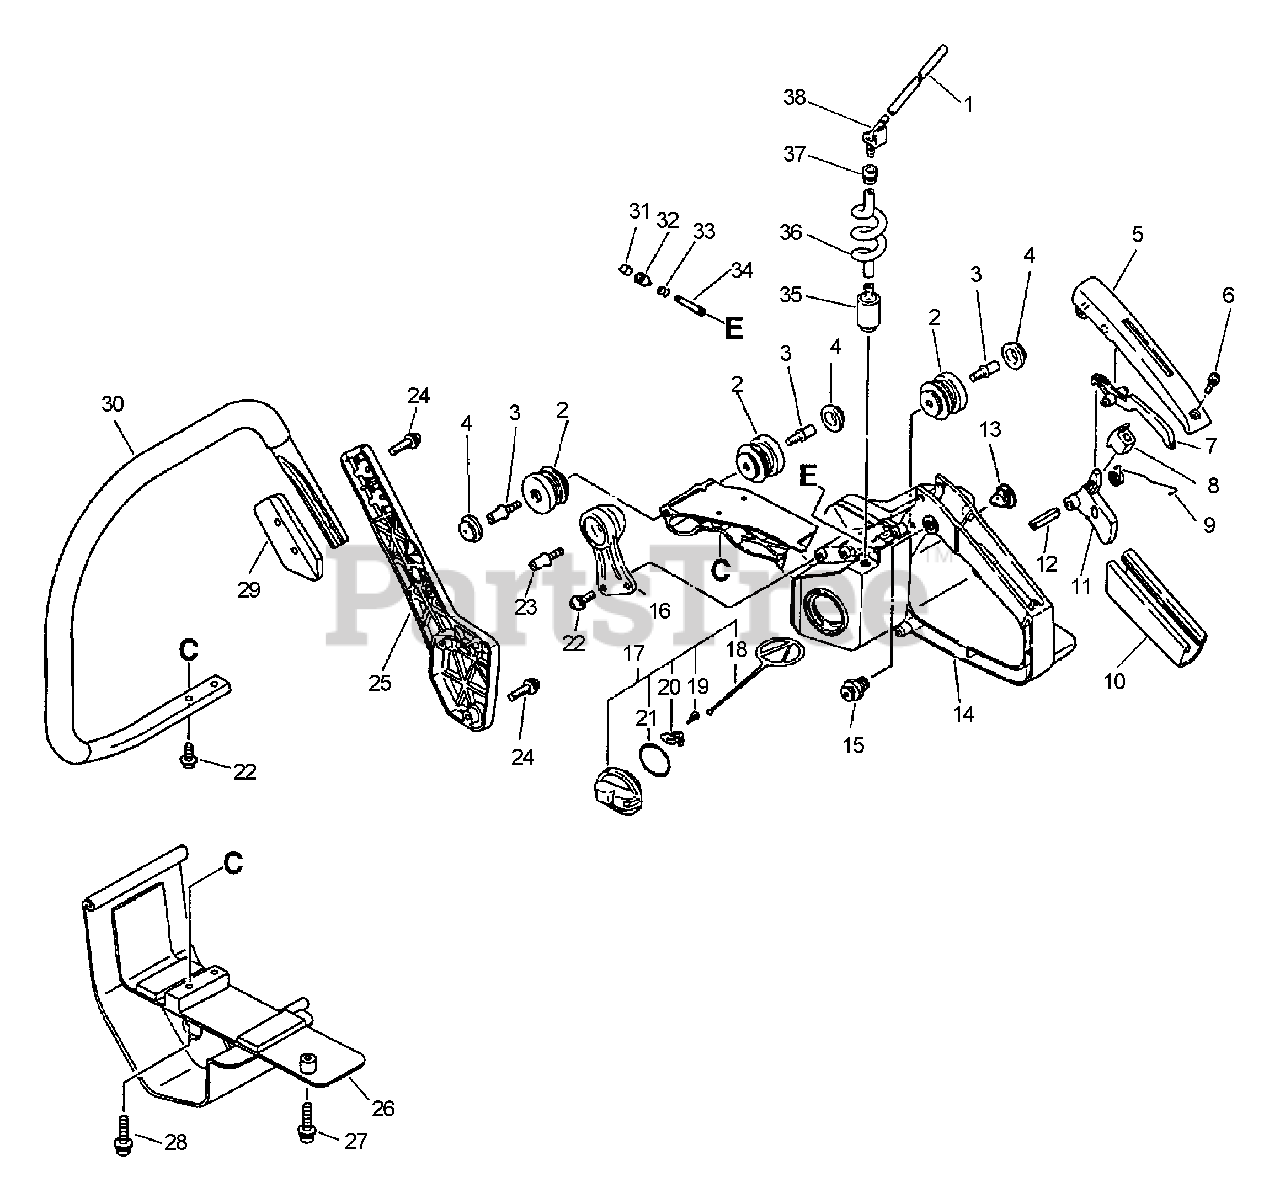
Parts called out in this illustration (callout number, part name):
1	PIPE - 3X6X100 -- BLACK
4	CAP, CUSHION
5	COVER, HANDLE
6	SCREW - 4X14
7	LEVER, TRIGGER LOCKOUT
9	SPRING, TRIGGER
10	GRIP, HANDLE
11	TRIGGER, THROTTLE
12	PIN - SPRING -- 5X25
14	HANDLE - REAR
15	LATCH, THROTTLE
17	CAP ASSY
18	CONNECTOR, CAP
19	SCREW - 3X8
20	RETAINER
21	O-RING - 29
22	SCREW - 5X14
24	SCREW - 5X20
25	BRACKET, HANDLE - OUTER
25	BRACKET, HANDLE
27	SCREW - 5X25
28	SCREW - 5X30
29	BRACKET, HANDLE - INNER
29	BRACKET, HANDLE
30	HANDLE - FRONT
31	VENT, FUEL TANK
32	COVER, VENT
33	CLIP - 5.5
34	PIPE - VENT
35	FILTER, FUEL
36	PIPE - BLACK
37	GROMMET
38	CONNECTOR, PIPE
